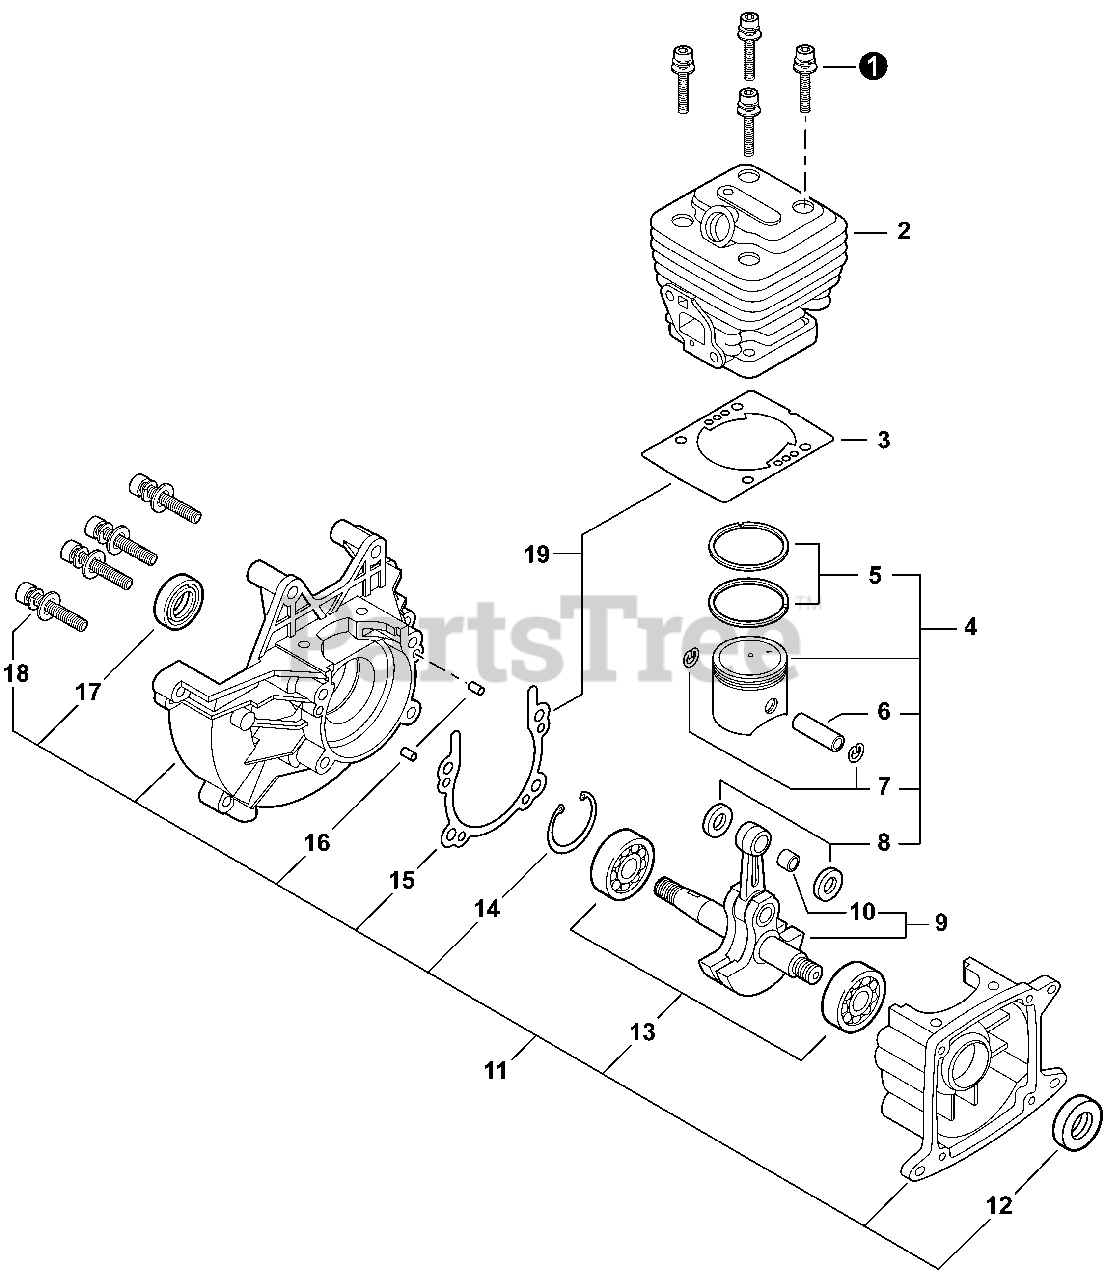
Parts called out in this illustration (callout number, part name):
1	BOLT 5×22
2	CYLINDER
3	GASKET, CYLINDER
4	PISTON KIT
5	RING, PISTON
6	PIN, PISTON 5×8×25.5
7	RING, SNAP
8	WASHER, THRUST 8.2×13×0.5
9	CRANKSHAFT ASSY
10	BEARING, NEEDLE 8
11	CRANKCASE ASSY
12	SEAL, OIL 12
13	BEARING, BALL 6001
14	RING, SNAP 28
15	GASKET, CRANKCASE
16	PIN, LOCATING 4×8
17	SEAL, OIL 12
18	BOLT 5×25
19	GASKET KIT
